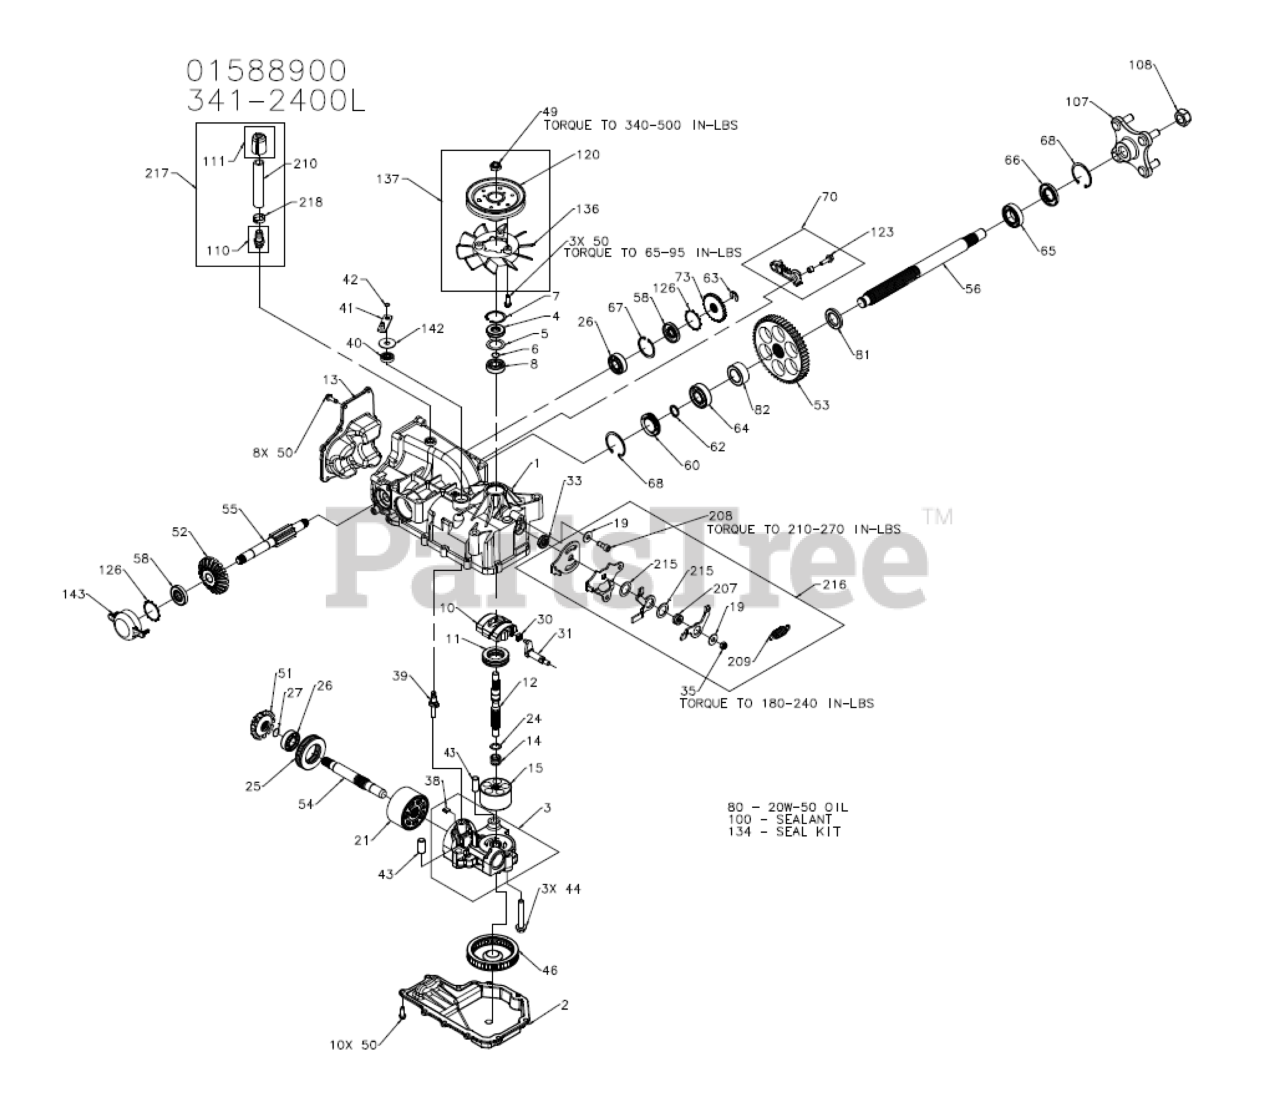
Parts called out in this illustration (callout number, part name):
1	KIT, MAIN HOUSING
2	HSG, IZT LOWER
3	KIT, C-SECTION
4	SEAL, LIP 15X35X7
5	WASHER .98X1.37X.04
6	RING, WIRE RETAINING
7	RING. RETAINING
8	BEARING, SHAFT BALL
10	SWASHPLATE. VARIABLE
11	BEARING. THRUST 30 X 52 X 13
12	SHAFT, INPUT
13	COVER, END IZT
14	SPRING. BLOCK
15	KIT, 10 CC BLOCK
21	ASSEMBLY BLOCK
24	WASHER. THRUST .59 X .79 X .04
25	BRG, THRUST BALL 42X68X16
26	BRG, BALL 17X40X12
27	RING, RET WIRE .561 ID
30	GUIDE. SLOT
31	ARM. TRUNNION TAPERED SQUARE
33	SEAL, LIP 12X25X7
35	NUT, LOCK, 5/16-24 UNF
38	KIT, BYPASS PLATE
39	ACTUATOR, BYPASS
40	SEAL, LIP
41	ARM. BYPASS
42	RING, RETAINING
43	PIN-HOLLOW .39X.5X1.
44	HFHCS 3/8-24X2.5 (PATCH)
49	HEX LOCK NUT, 1/2-20 (NYLON INSERT)
50	HFHCS 1/4-20X.75
51	GEAR, BEVEL 14T
52	GEAR, BEVEL 19T
53	GEAR, SPUR 53T
54	SHAFT, MOTOR
55	SHAFT, BRAKE
56	AXLE, 1.0X12.3
58	SEAL, LIP 17X40X7
60	PLUG, SEAL 1.86
62	RING, RET .75 EXT
63	RING, RET .440 EXT
64	BRG, BALL 20X47X14
65	BRG, BALL 25X47X12
66	SEAL, LIP 25X47X7
67	RING, RET 1.56 INT
68	RING, RET 1.87 INT
70	BRAKE ARM, LH IZT
73	BRAKE, PARK SPLINE
80	FLUID, HYDRO 20W50 QT
80	FLUID, HYDRO 15W50 QT
100	SEALANT TUBE 10.1OZ.
107	ASSEMBLY, HUB
110	FTG-STR .50 O-RING
111	BREATHER ASSEMBLY
120	PULLEY, 4.5 IN
123	SCREW, HFH 1/4-28 X 7/8 PATCH
126	RING, RET 1.43"
134	KIT, SEAL
136	FAN-6IN
137	KIT, FAN/PULLEY
142	WASHER, .392 X 1.250 X .0
143	CAP, BRAKE
207	SPACER, TRUNNION
208	SHCS 5/16-24X.75
209	SPRING, EXTENSION
210	HOSE .5X4
215	Assembly, RTN
216	KIT, CCW RTN SCISSOR
217	KIT, BREATHER
